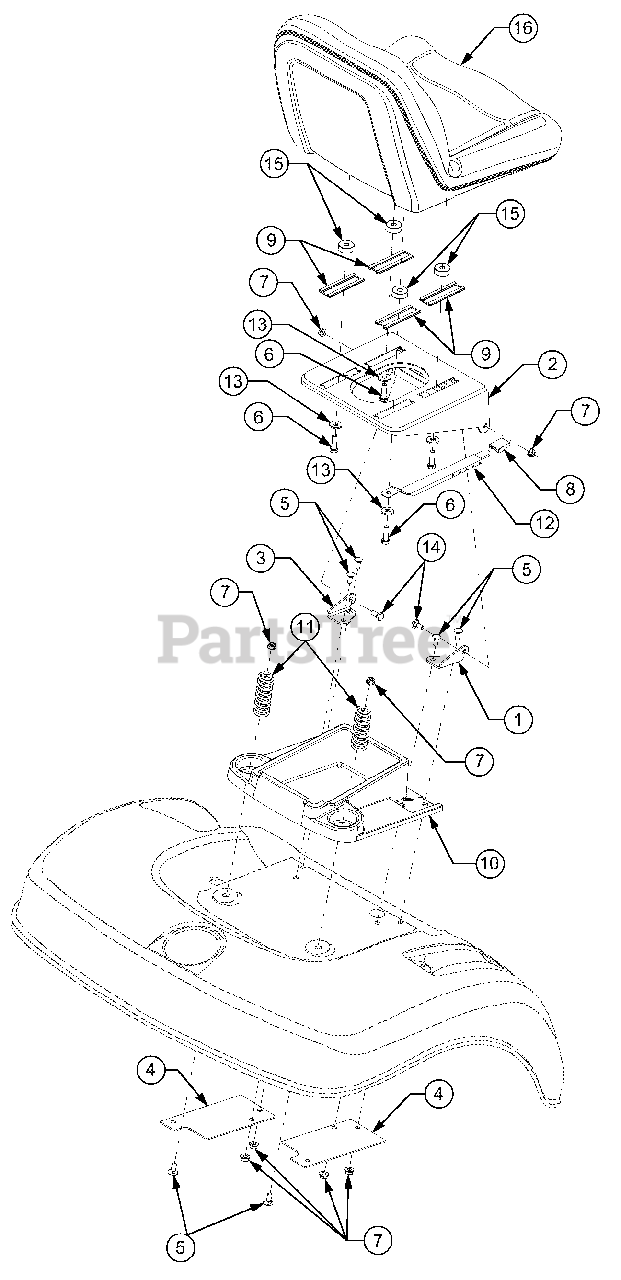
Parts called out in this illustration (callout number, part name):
6	Screw, Hx Cap Lock, 3/8-16 x 1.25 GR5
7	Nut, Hex Flange Lock, 5/16-18
8	Knob, Seat Adjuster
9	Slide, Seat
10	Tray, Tool
11	Spring, Comp, 1.9 OD x 2.4
12	Adjuster, Seat
13	Washer, Flat, .406 x 1.0 x .105
14	Bolt, Shoulder
15	Spacer, Seat Slide Shoulder
16	Seat, High Back
